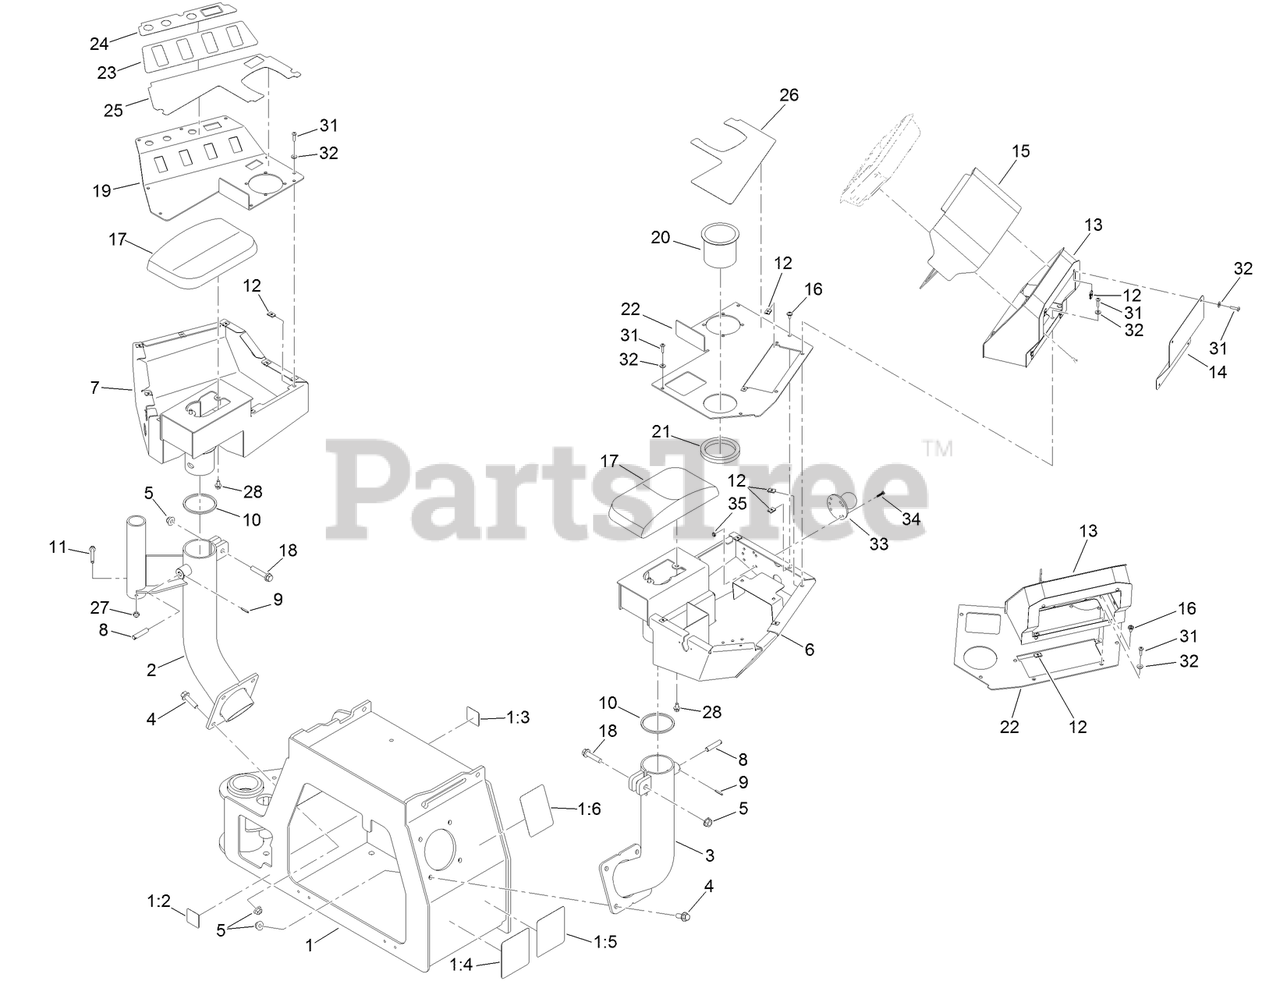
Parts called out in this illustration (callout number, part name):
1	OPERATOR CONSOLE ASM
1:2	DECAL-SEAT ADJUST
1:3	DECAL-SEAT ADJUST
1:4	DECAL-DANGER, SHOCK
1:5	DECAL-DANGER, NO RIDERS (FRONT)
1:6	DECAL-DANGER, BACK UP
2	ARM-CONSOLE, LH
3	ARM-CONSOLE, RH
4	SCREW-HHF
5	NUT-HF, NI
6	CONSOLE-RH
7	CONSOLE-LH
8	PIN-W/CROSS HOLE
9	SCREW-HH
10	RING-WEAR, CONSOLE ARM
11	SCREW-HHF
12	NUT-SPEED
13	COVER-DISPLAY
14	PLATE-BOTTOM ARM, RH
15	VISOR-DISPLAY
16	SCREW-PPH
17	PAD-ARM
18	SCREW-HHF
19	PLATE-CONSOLE TOP, LH
20	HOLDER-CAN, BEVERAGE
21	RING-RUBBER
22	PLATE-CONSOLE SIDE, RH
23	DECAL-CONTROL SWITCHES
24	DECAL-CONTROL INDICATORS
25	DECAL-LEFT JOYSTICK
26	DECAL-RIGHT JOYSTICK
27	NUT-HF
28	SCREW-HHF
31	SCREW-PPH
32	WASHER-FLAT
33	MOUNT-RAM (2-1/2 DIA BASE W/1.5)
34	SCREW-PHPH SST
35	NUT-LOCK
